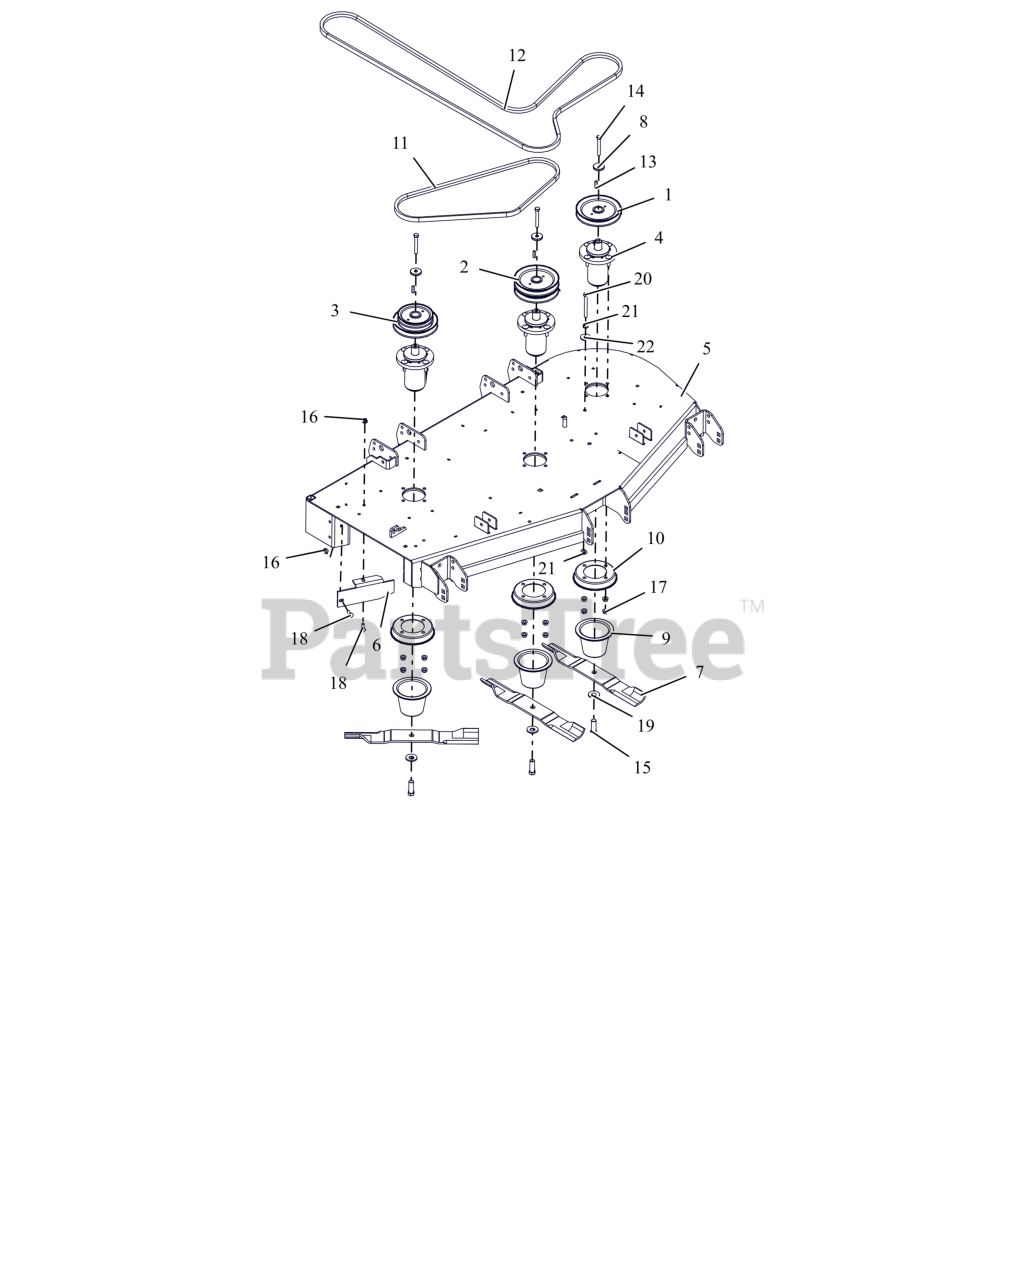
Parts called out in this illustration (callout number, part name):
1	PULLEY, SINGLE-1"ID X 6" OD
2	PULLEY, DOUBLE
3	PULLEY, DBL-1"IDX6.00"&4.75"OD
4	ASM, MAINT FREE ALUM SPINDLE
5	WLDMT, PT152 SIDE DISCH DECK (RED)
6	52" DISCHARGE BAFFLE - RED
7	BLADE, 18.00" MOWER (HI-LIFT)
8	RETAINER, SHEAVE
9	GUARD, SPINDLE LOWER
10	GUARD, SPINDLE TOP
11	V-BELT, B-COGGED
12	BELT, B-SECTI0N EPDM RAW EDGE
13	KEY, SQ .25X.25X1.00 RC 40-50
14	BLT, HEX .38-16X2.75 G8 ZCC
15	BLT, HEX .62-18X1.75 G8 ZCC
16	NUT,NYL-FLG .31-18 GF ZCC
17	NUT-LK-CTR-FLG .375-16 GF ZCC
18	BLT,RHSN .31-18X1.00 G5 ZCC
19	WSHR-BLVL .669X1.535X.138
20	BLT, HEX .38-16X3.50 G5 ZCC
21	NUT, SPNLK-FLG .38-16 G5 ZCC
22	WSHR,FLT .406X1.375X.135 ZCC
